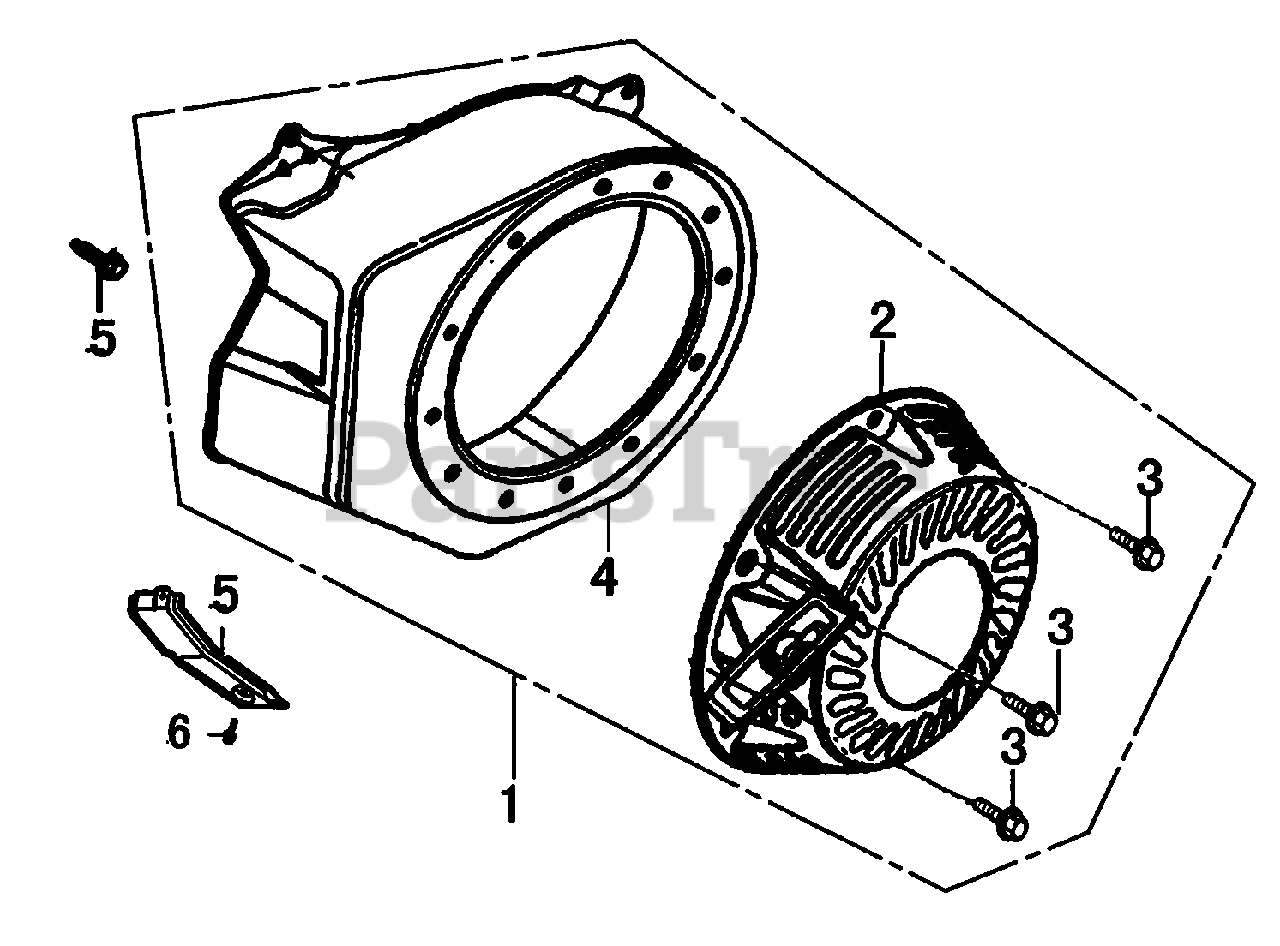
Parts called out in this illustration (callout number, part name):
1	STARTER, RECOIL W/BLWR HSNG.
2	STARTER ASSY., RECOIL
3	BOLT, FLANGE 6X8
4	HOUSING, BLOWER
5	BOLT, FLANGE 6X12
